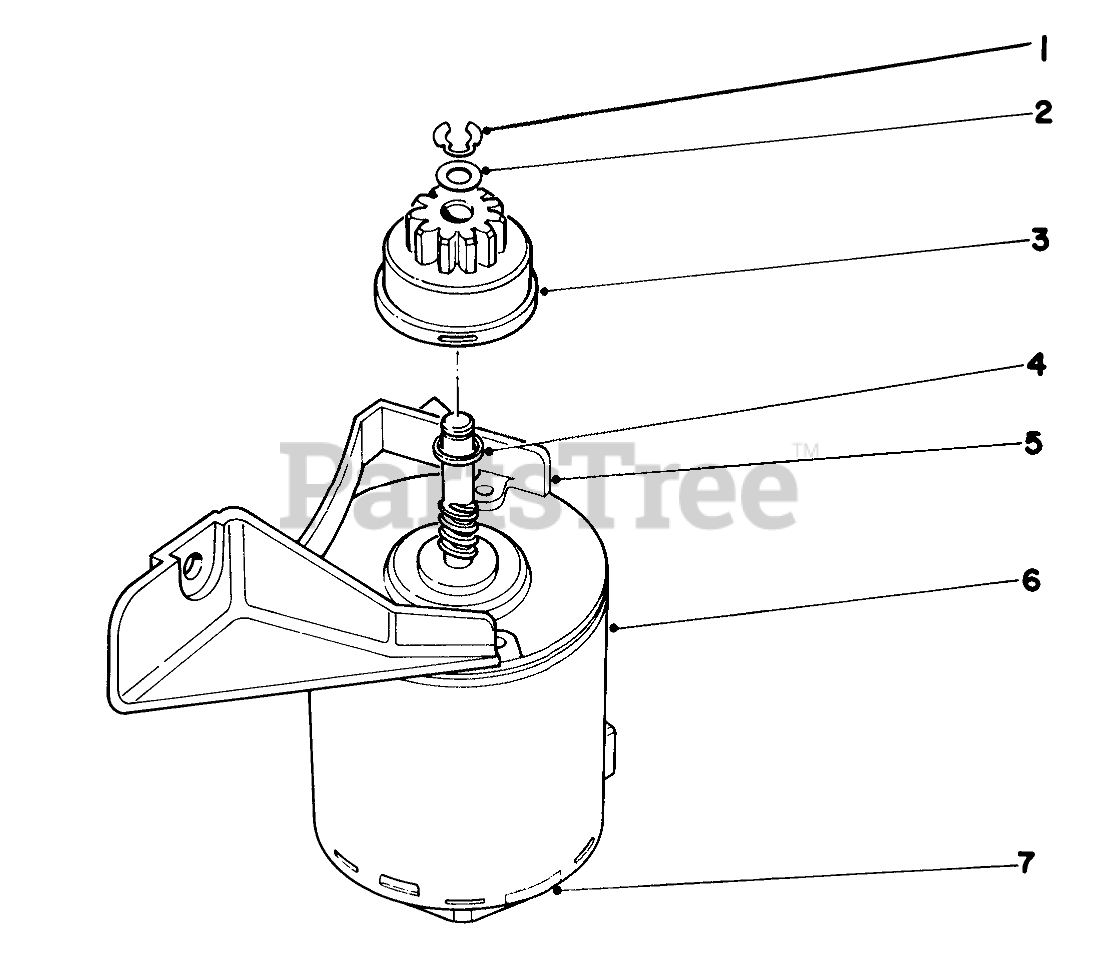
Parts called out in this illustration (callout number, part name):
1	RING-RETAINING
2	WASHER
3	PINION ASM
4	Spacer
5	Mounting Bracket
6	Starter Motor
7	End Plate
